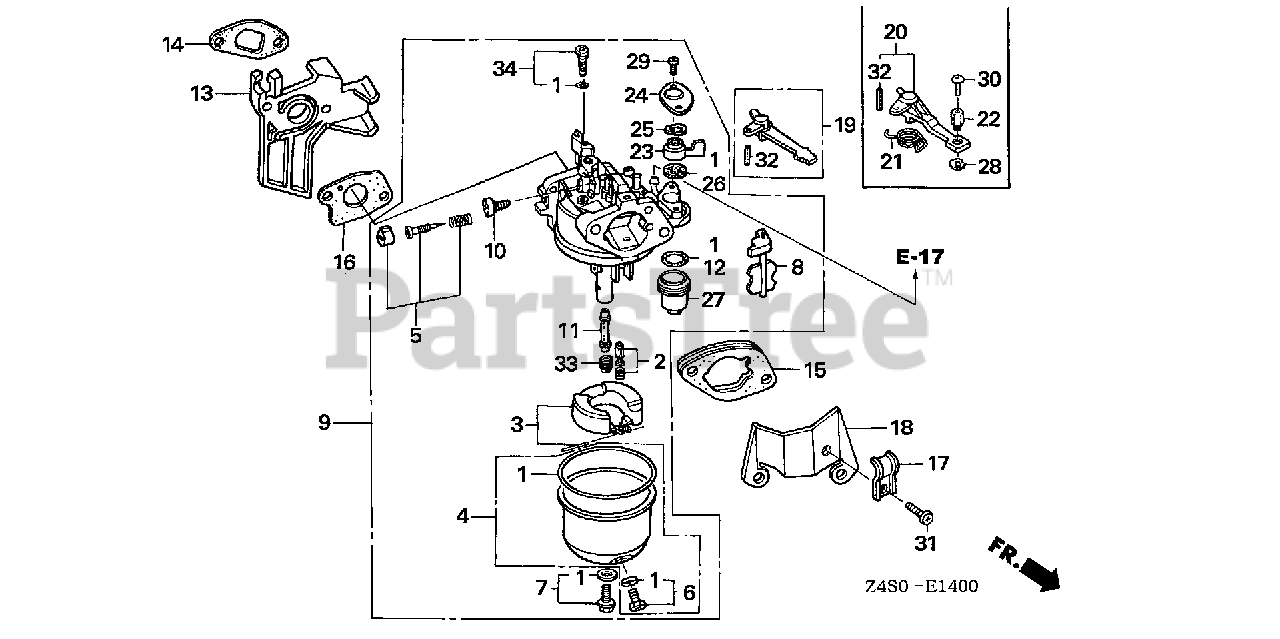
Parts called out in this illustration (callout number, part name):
1	GASKET SET
2	VALVE SET, FLOAT (SEAT NOT INCLUDED)
4	CHAMBER SET, FLOAT
5	SCREW SET, PILOT
6	SCREW SET, DRAIN
7	SCREW SET
9	CARBURETOR ASSY. (BE64B B/C)
10	SCREW, THROTTLE STOP
11	NOZZLE, MAIN
12	GASKET, FUEL STRAINER CUP
13	INSULATOR, CARBURETOR
14	GASKET, INSULATOR
15	SPACER, CARBURETOR
16	GASKET, CARBURETOR
19	LEVER, CHOKE (STD)
23	LEVER, PETCOCK
24	PLATE, LEVER SETTING
25	SPRING, PETCOCK LEVER
26	GASKET, PETCOCK
27	CUP, FUEL STRAINER
29	SCREW, PAN (3X6)
32	PIN, SPRING (2X12)
33	JET, MAIN (#72)
33	JET, MAIN (#68)
33	JET, MAIN (#70)
34	JET SET, PILOT (#45)
